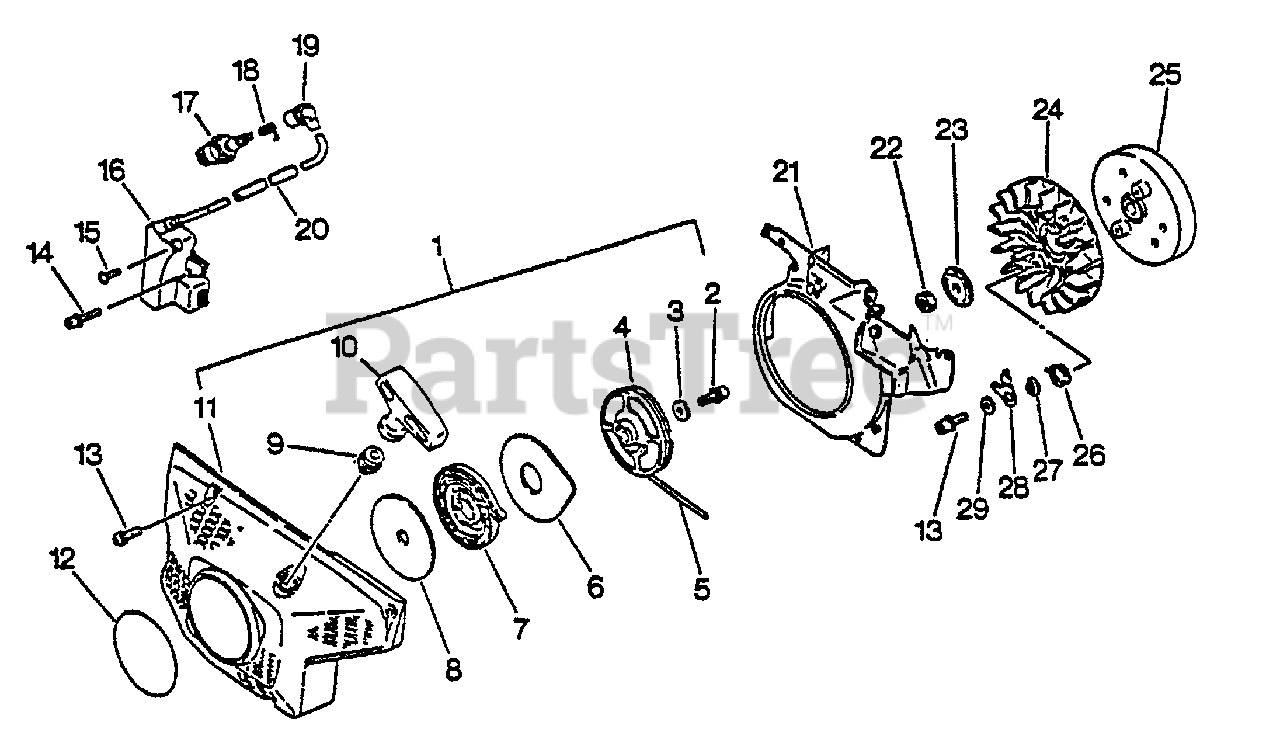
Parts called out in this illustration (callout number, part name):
1	STARTER ASSY
2	BOLT 5×14
3	WASHER 5.5×12×0.8
4	REEL, ROPE
5	ROPE, STARTER 4.0×950
6	PLATE, STARTER
7	SPRING, RECOIL
8	PLATE, STARTER
9	GUIDE, ROPE
10	GRIP, STARTER
11	CASE, STARTER
12	LABEL - ECHO
13	BOLT 5×20
14	BOLT 4×20
15	SCREW 4×8
16	COIL, IGNITION
17	SPARK PLUG - BPM6A
18	TERMINAL, SPARK PLUG
19	CAP, SPARK PLUG
20	PIPE
21	SHIELD, FAN
23	WASHER 8.2×31×0.8
25	FLYWHEEL
26	SPRING, RETURN
28	PAWL, STARTER
29	WASHER 5.5×12×0.8
